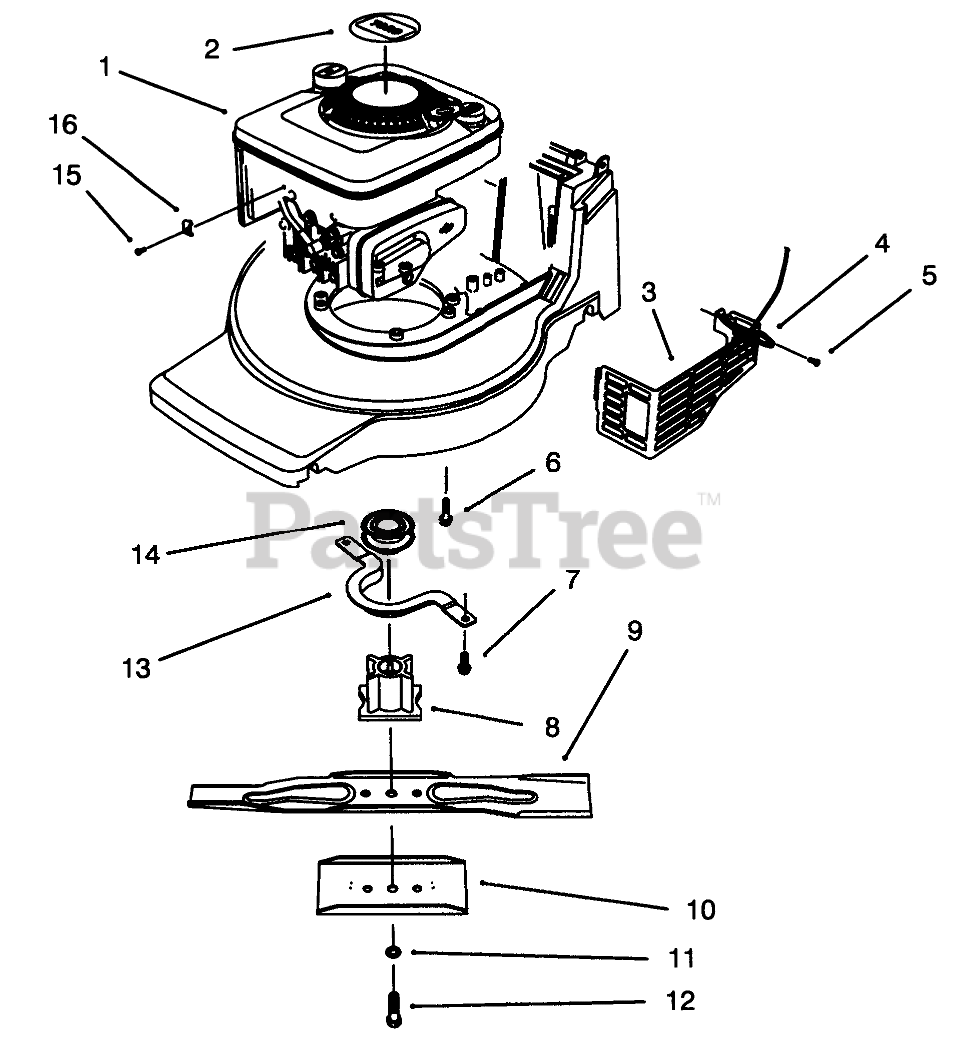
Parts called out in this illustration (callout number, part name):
1	Engine-B & S Quantum
2	DECAL - RECOIL
3	SHIELD - MUFFLER
4	TIE-CABLE
5	SCREW-HWH
6	SCREW-HWH
7	SCREW-HWH
8	BLADE RETAINER - 25 MM
9	Blade
10	Stiffener Blade
11	WASHER-LOCK
12	BOLT-BLADE
13	Guide-Belt
14	PULLEY-DRIVE, ZONE START
15	CLAMP SCREW F/W ENGINE
16	CLAMP-CASING
